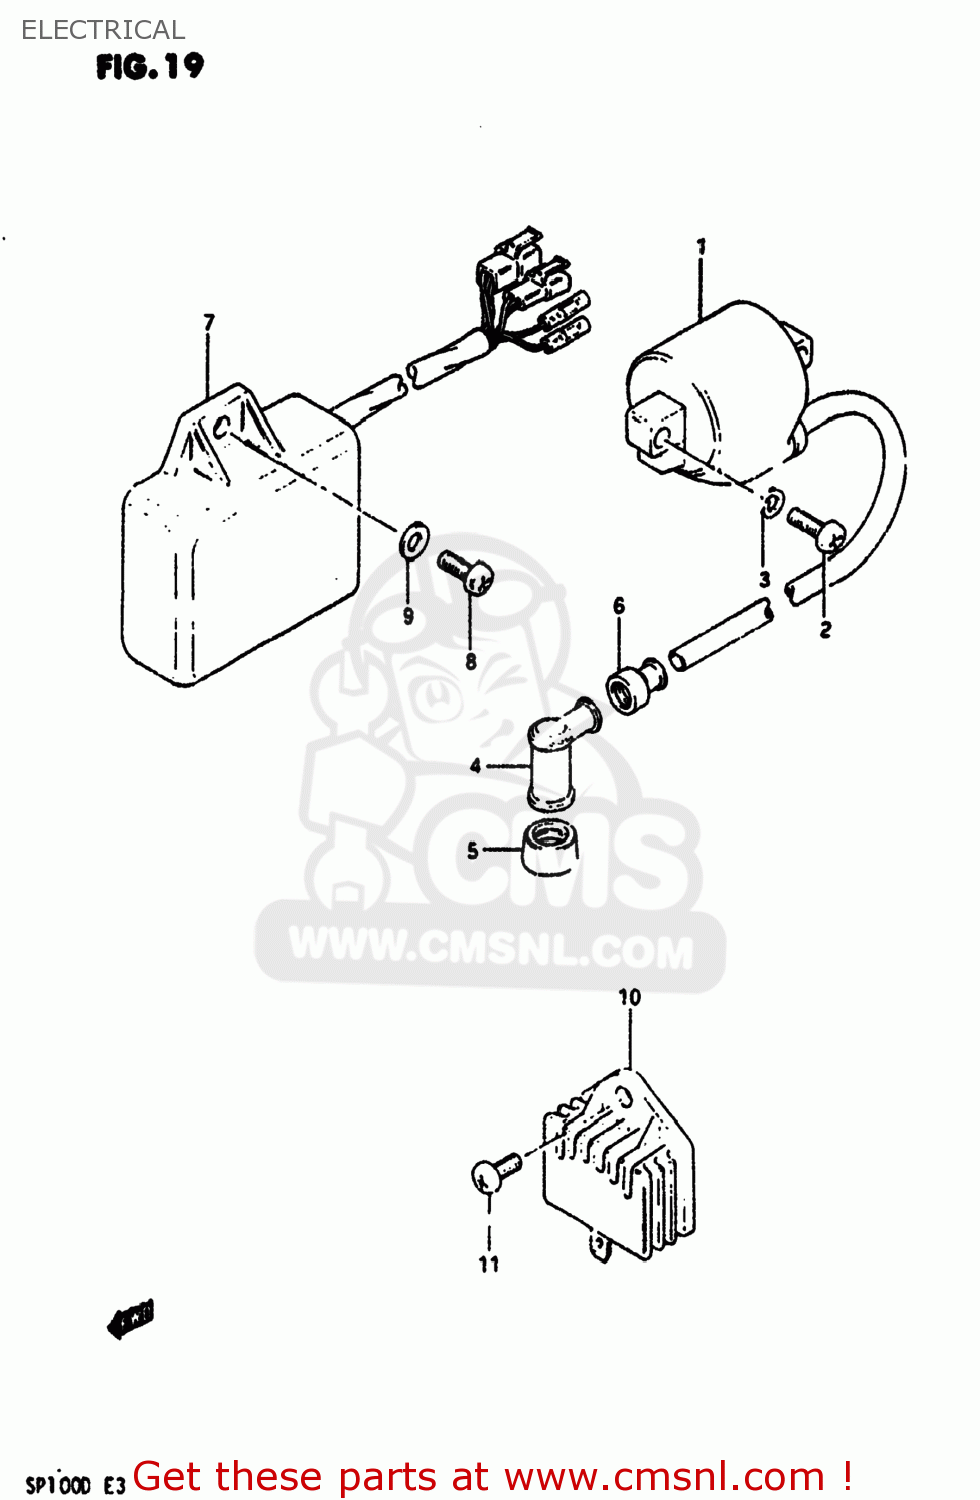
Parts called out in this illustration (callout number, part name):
1	COIL ASSEMBLY,IGNITION
2	SCREW
3	LOCK WASHER
4	CAP ASSY,SPARK PLUG
5	SEAL,SPARK PLUG
6	SEAL,SPARK PLU
7	CDI UNIT
8	SCREW
9	WASHER
10	RECTIFIER ASSY,REGULATOR
11	SCREW 6X12
